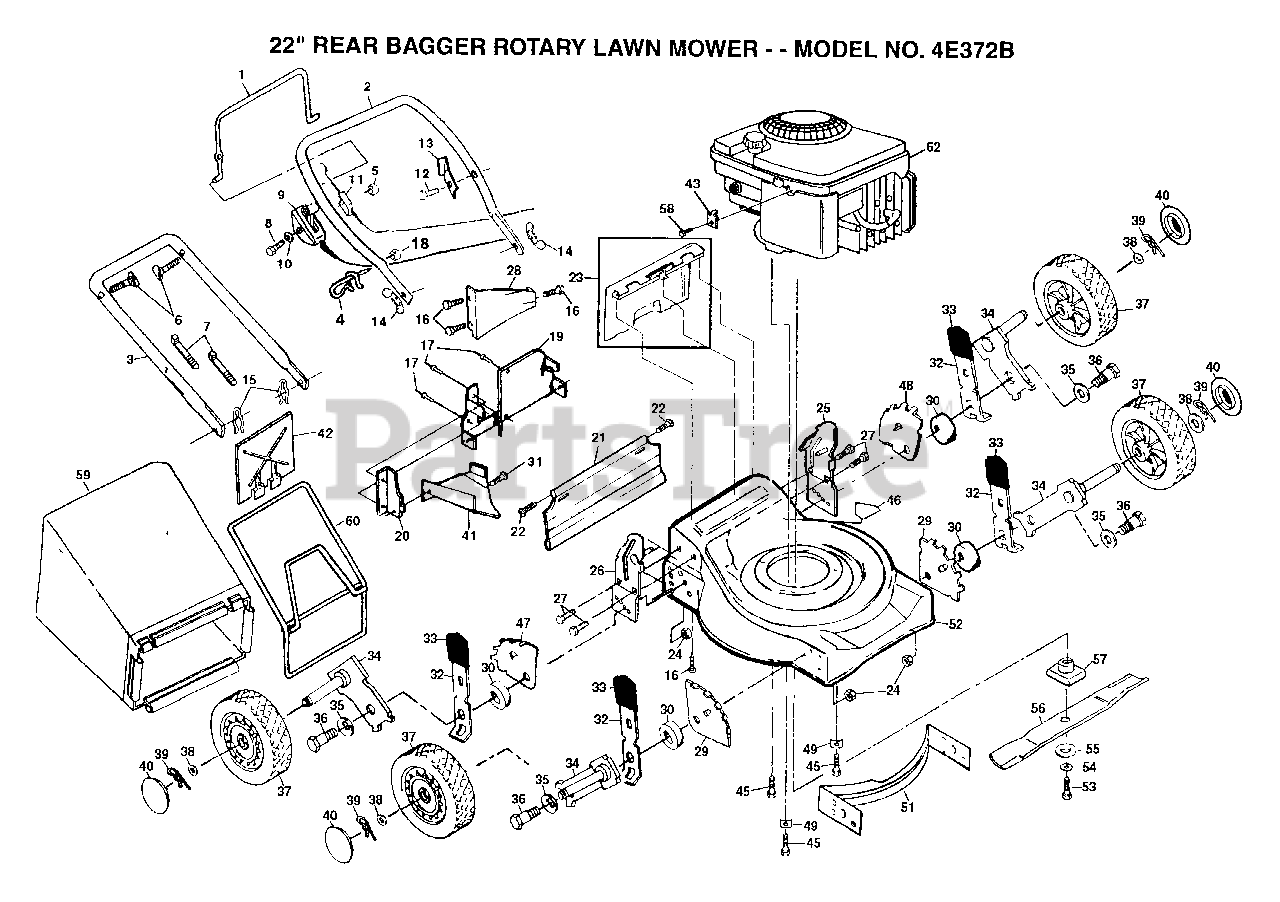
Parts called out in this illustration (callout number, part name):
1	CONTROL BAR
4	ROPE GUIDE
6	BOLT.HANDLE.LM
9	CNTL.THROT.47.5
10	WASHER PM
11	"CABLE,ENG ZONE CO"
12	TAPPING SCREW
13	"BRKT,UPSTOP"
14	"NUT,WING PM"
15	HAIRPIN COTTER
16	SCREW
17	BLIND RIVET
18	NUT
19	PLATE.BACK
22	HINGE SCREW
24	LOCKNUT PM
27	SCREW
28	REAR BAFFLE
29	BRACKET.ADJ.9POS.
31	SCREW PM
32	SPRING SELECTOR
33	KNOB PM
34	AXLE ARM
35	"WASHER, BELLEVIL."
38	WASHER
39	RETAINER CLIP PM
40	HUB CAP
41	DISCHARGE BAFFLE
42	MULCHER PLATE
43	CABLE CLAMP
45	SCREW
46	DECAL HYT
47	BRACKET.ADJ.9.RH
48	BRACKET.ADJ.9.LH
52	KIT.HSG.22RD.PUSH
53	SCREW
54	LOCKWASHER
55	"WASHER,HARDEN"
57	ADAPTOR.BLADE.LM
58	SCREW PM
59	GRASS BAG
60	CATCHER FRAME
